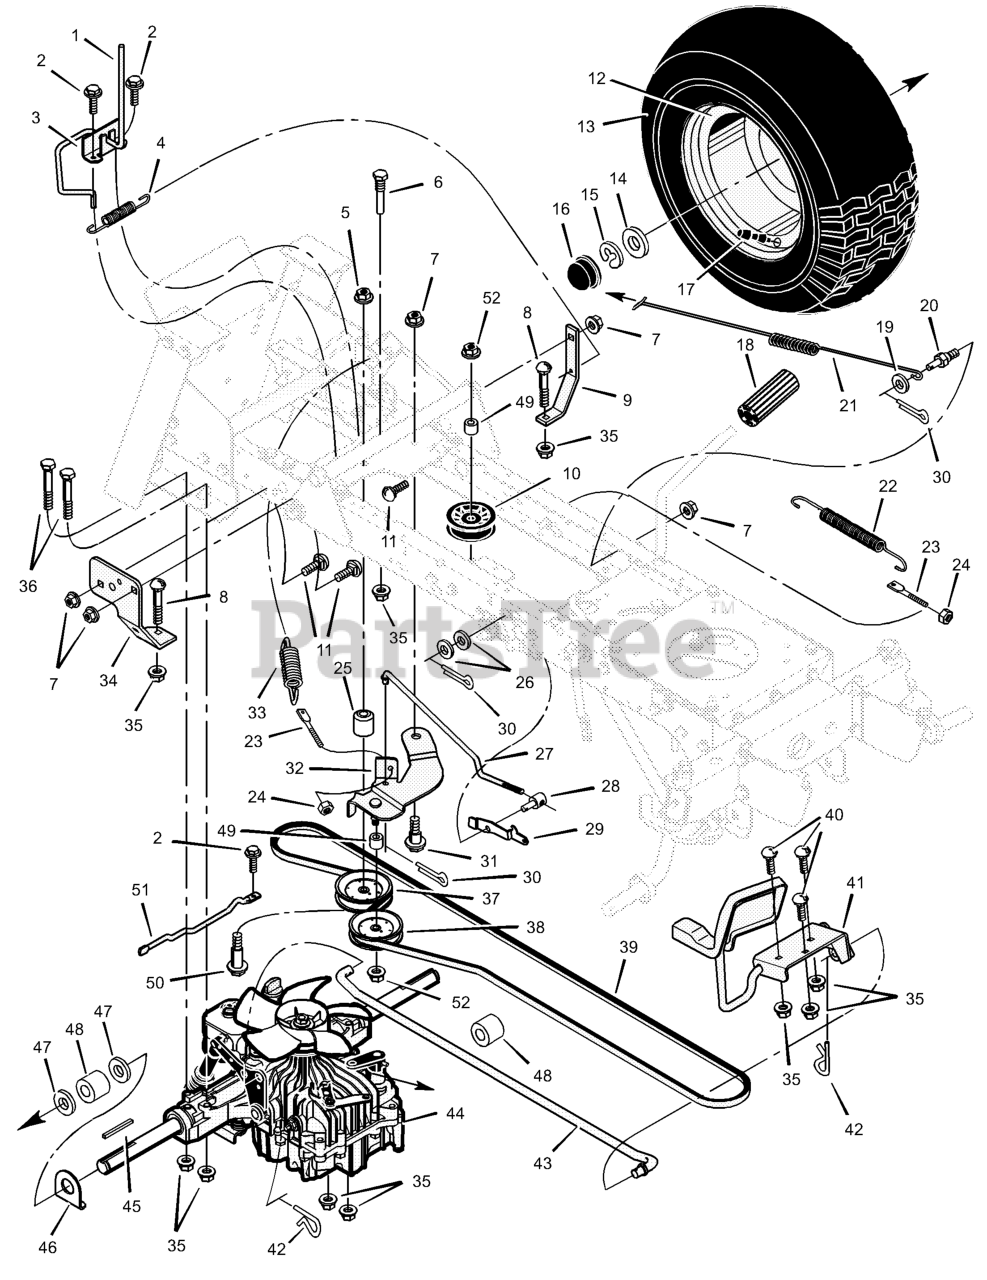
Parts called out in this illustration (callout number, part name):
1	Rod, Cable
3	Bracket, Cable
4	Spring, Extension
5	Locknut
6	Guide, Belt
7	Locknut
8	Bolt, Carriage
9	Bracket, Torque
10	Pulley, Idler
11	Bolt, Carriage
12	Assembly, Wheel and Tire
13	Tire Only *
16	Cap, Hub
17	Stem, Valve
18	Pedal
19	Washer
20	Stud, Threaded
21	Spring, Extension
22	Spring - Extension
23	Stud, Spring Mount
24	Locknut, Flange
25	Spacer
27	Rod, Clutch
28	Nut, Adjusting
29	Latch, Parking Brake
30	Pin, Cotter
31	Bolt, Shoulder
32	Assembly, Idler Arm
33	Spring, Extension
34	Bracket, Torque
35	Nut, Flange
36	Bolt
37	Pulley, Backside Idler
38	Pulley, "V" Idler
39	Belt, Drive
40	Bolt, Carriage
41	Assembly, Pedal
42	Pin, Hair
43	Rod, Hydro Control
44	Transaxle, Hydro **
45	Key, Square
46	Washer, Thrust
47	WASHER, 1-1.3 16G FLT
51	Guide, Belt
52	Locknut
